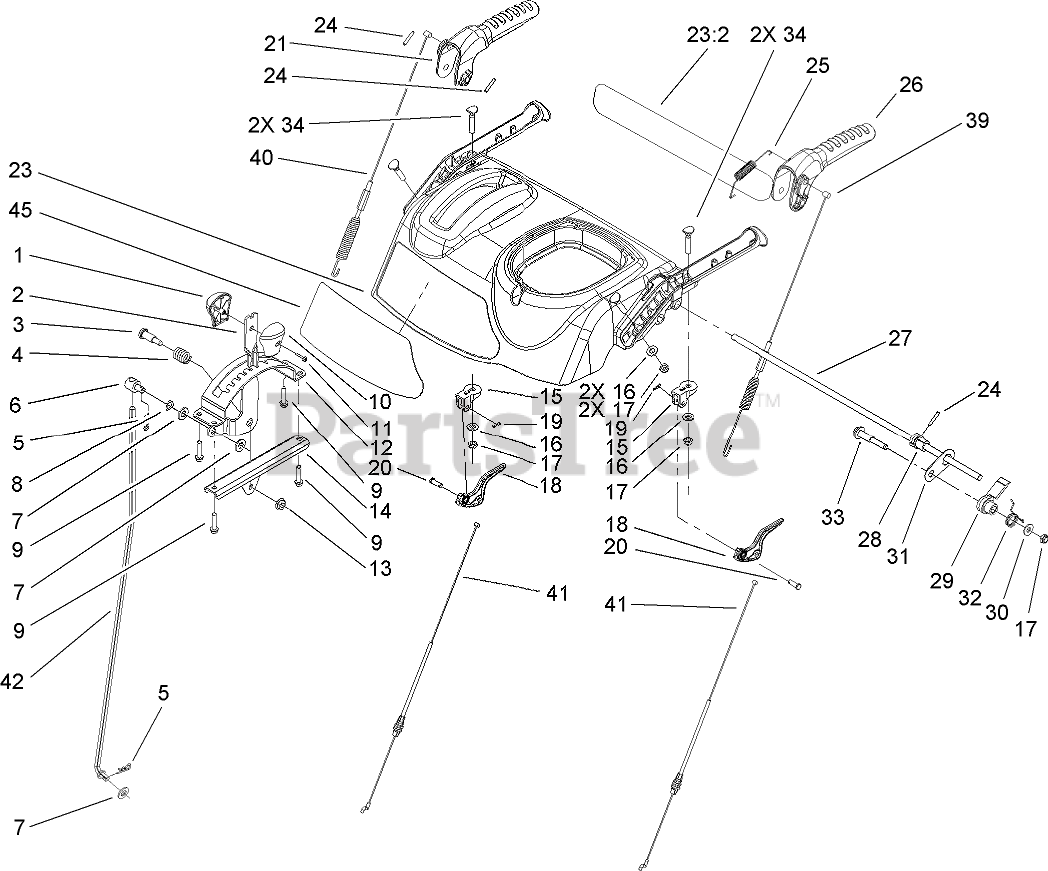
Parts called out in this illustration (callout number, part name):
1	KNOB-SHIFT, RH
2	SELECTOR-SPEED
3	SCREW-SHOULDER
4	SPRING-COMPRESSION
5	PIN-COTTER
6	TRUNNION
7	WASHER-FLAT
8	WASHER-SPRING
9	SCREW-PLASTITE
10	KNOB-SHIFT, LH
11	SCREW-PPH
12	GUIDE-SELECTOR, SPEED
13	NUT-HF
14	MOUNT-SELECTOR, SPEED
15	MOUNT-CLUTCH, LEVER
16	WASHER-FLAT
17	NUT-LOCK, NI
18	LEVER-CLUTCH
19	PIN-HAIR
20	PIN-CLEVIS
21	LEVER-AUGER
23	CONTROL PANEL ASM
24	PIN-SPRING
25	SPRING-TENSION
26	LEVER-TRACTION
27	ROD-LOCKOUT
28	CAM-LOCKOUT
29	LATCH-LOCKOUT
30	WASHER-FLAT
31	LINK-LOCKOUT
32	SPRING-TORSION
33	SCREW-SHOULDER
34	SCREW-HANDLE
39	CABLE-TRACTION
40	CABLE-AUGER
41	CABLE-CLUTCH
42	ROD-SHIFT
